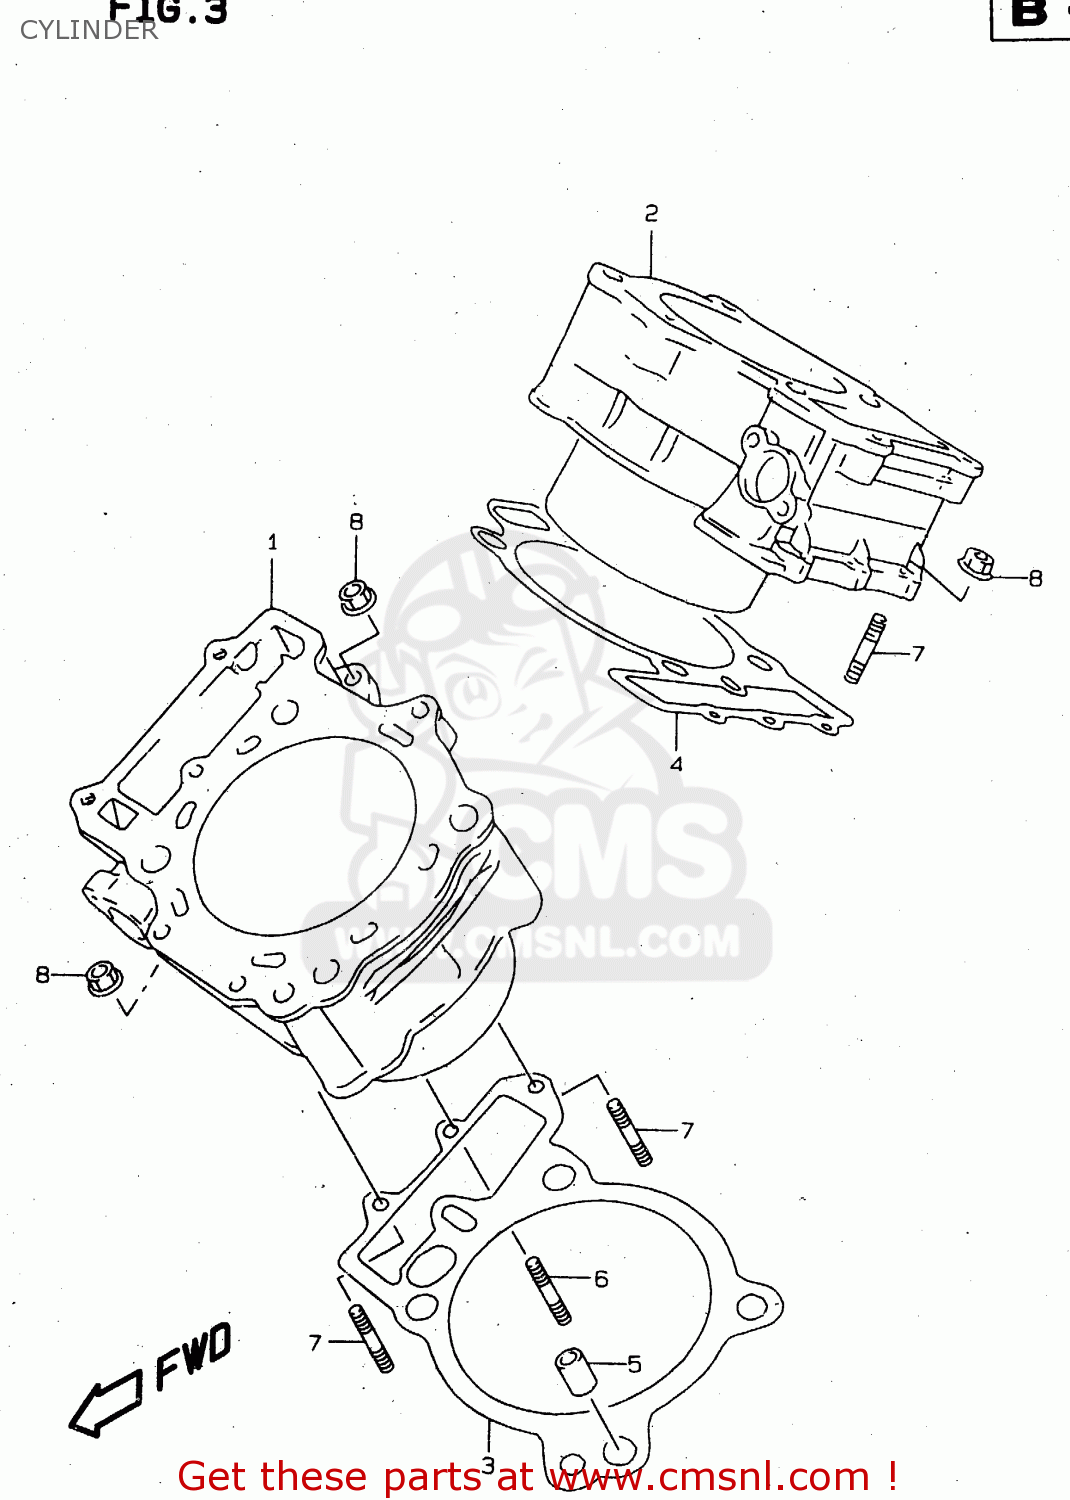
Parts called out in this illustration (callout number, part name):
1	CYLINDER,FRONT
2	CYLINDER,REAR
3	GASKET,CYLINDER FR (NAS)
4	GASKET,CYLINDER RR (NAS)
5	PIN
6	STUD BOLT (L:20)
7	STUD,M6X1X32
8	NUT
